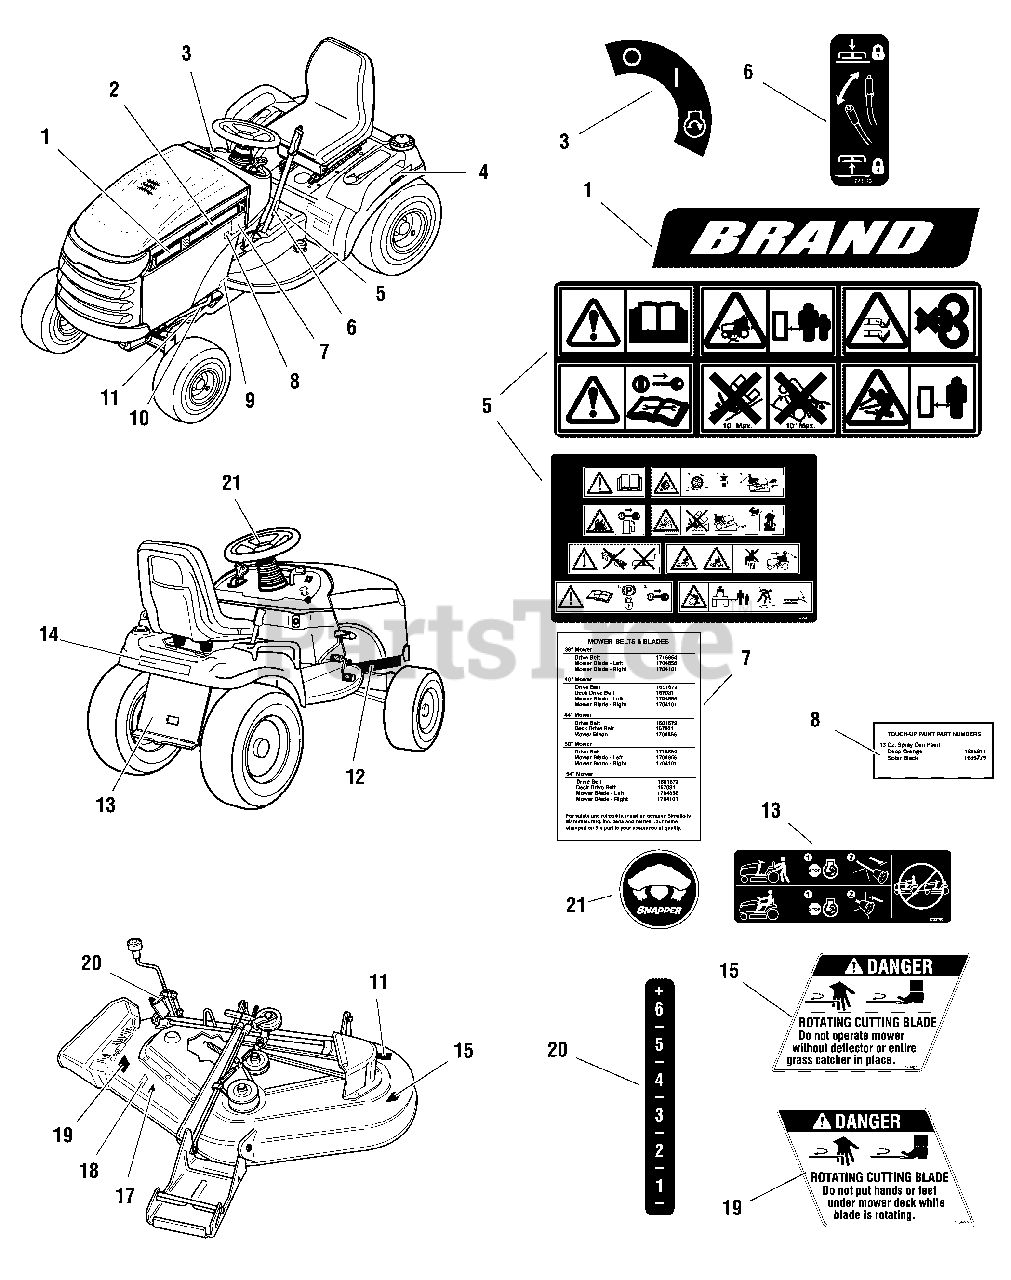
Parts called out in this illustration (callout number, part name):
1	DECAL, YT400 24HP
2	DECAL, Snapper, LH & RH
3	DECAL, Ignition Switch Symbols, White/Black
4	DECAL, Automatic Control Traction
5	DECAL, Tunnel Cover, Safety
6	DECAL, Lift Lever Symbols
7	DECAL, Drive Belts, Mower Blades
8	DECAL, Touch-Up Paint, Red
9	DECAL, Protective Sticker
10	LABEL, Decibel, Power Mass
11	DECAL, I.D. Plate
12	DECAL, Patent
13	DECAL, Transmission Release Valve
14	DECAL, Snapper, Rear
15	DECAL, Danger Do Not Put Hands/Feet in Mower
17	DECAL, OPEI Certified
18	DECAL, 52"
19	DECAL, Danger Do Not Operate Without Deflector
20	DECAL, Height of Cut
21	DECAL, Steering Wheel Icon
